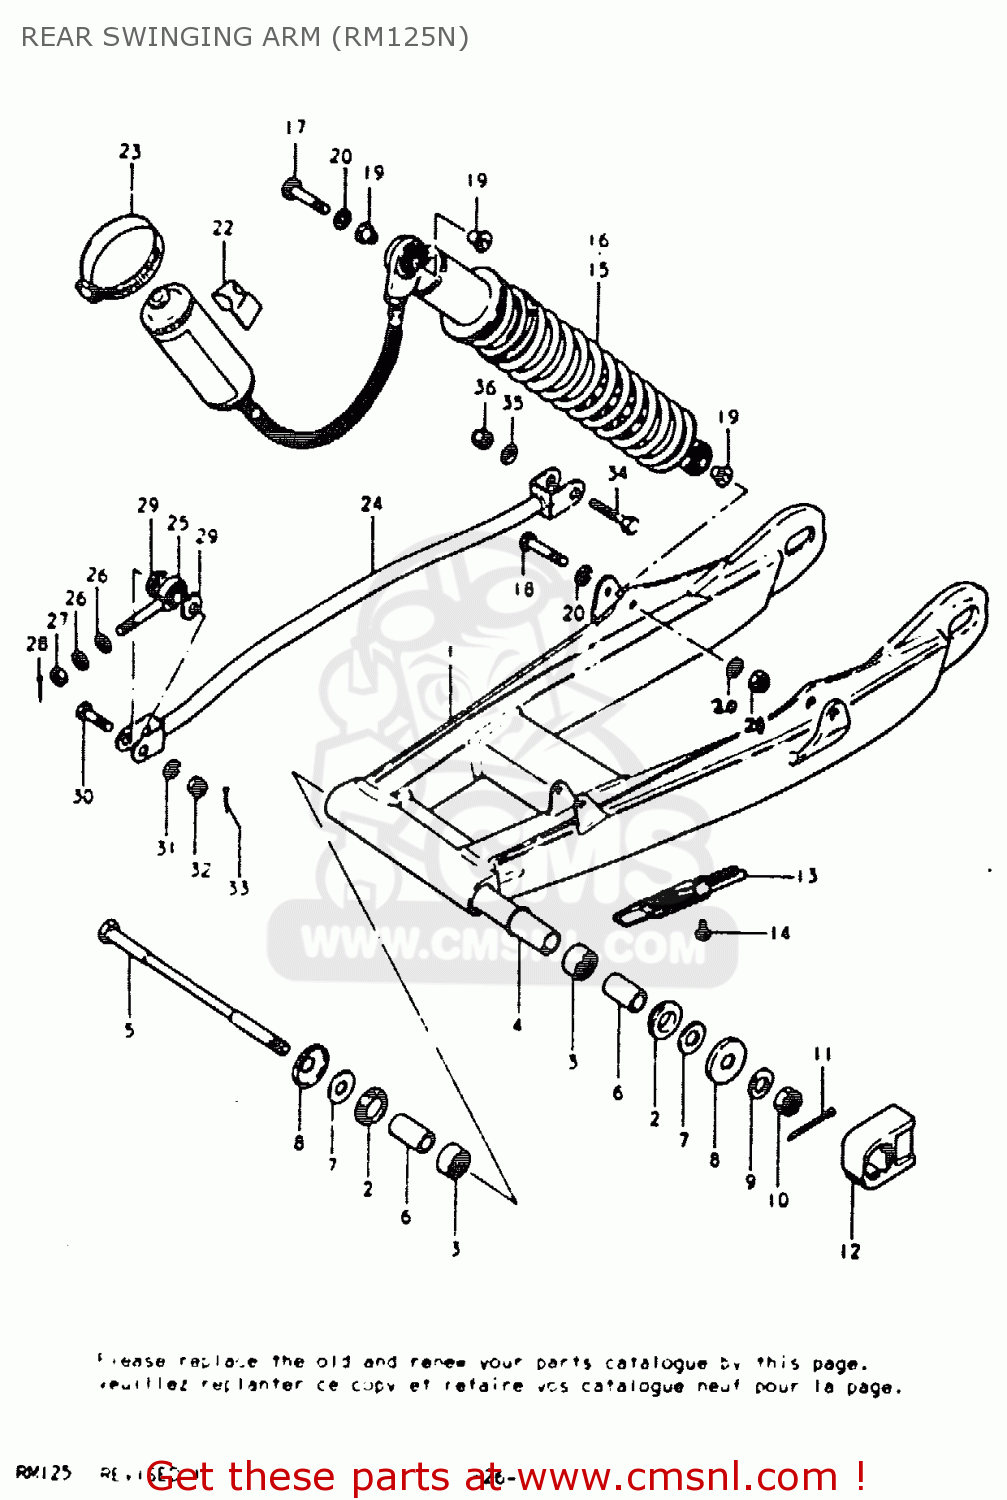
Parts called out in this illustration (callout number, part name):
1	SWING ARM ASSEMBLY,REAR
2	BUSH,RR SWINGINGARM PIVOT
3	ROLLER BEARING (17X24X2
4	SPACER,SWING ARM,CENTER
5	SHAFT,REAR SWING ARM
6	SPACER,RR SWGARM PIVOT
7	WASHER
8	COVER,REAR SWING ARM DUST
9	WASHER
10	NUT, REAR AXLE
11	COTTER PIN
12	BUFFER,CHAIN TOUCH DEFLECTOR
13	BUFFER,CHAIN TOUCH DEFLECTOR
14	SCREW
15	SHOCK ABSORBER ASSY, REAR
16	SHOCK ABSORBER ASSY, REAR
17	BOLT
18	BOLT(8X46)
19	SPACER,RR SHK ABS INNER
20	WASHER
21	NUT
22	CUSHION,RR SHOCK ABSORBER
23	CLAMP
24	TORQUE LINK,REAR
25	BEARING
26	WASHER
27	NUT
28	PIN
29	DUST SEAL,TORQUE LINK FR BRG
30	BOLT 8X28
31	WASHER
32	NUT 8MM
33	PIN 20X20
34	BOLT 10X40
35	WASHER
36	NUT
